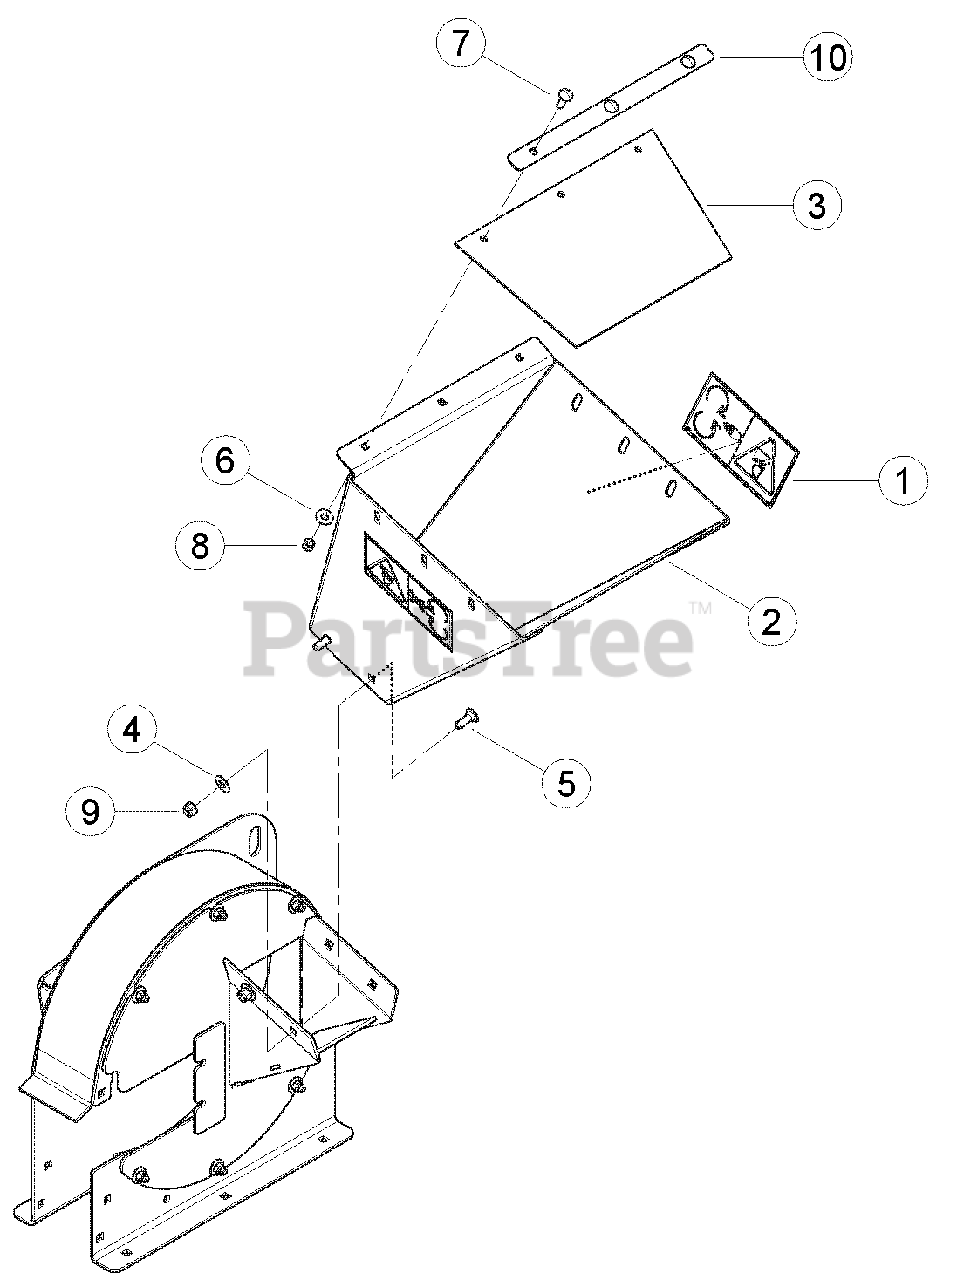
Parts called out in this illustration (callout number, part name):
1	DECAL, BLADE DANGER ISO
2	ASSEMBLY, HOPPER
3	FLAP, CHIPPER CHUTE
4	WASHER, 3/8 FLAT ZP
5	BOLT, 3/8 X 1 CRG GR5 NC ZP
6	WASHER, 5/16 FLAT ZP
7	BOLT, 5/16 X 1 CRG GR5 ZP
8	NUT, 5/16 NE NYLOCK ZP
9	NUT, 3/8 NE NYLOCK ZP
10	STRIP, FLAP RETAINER
